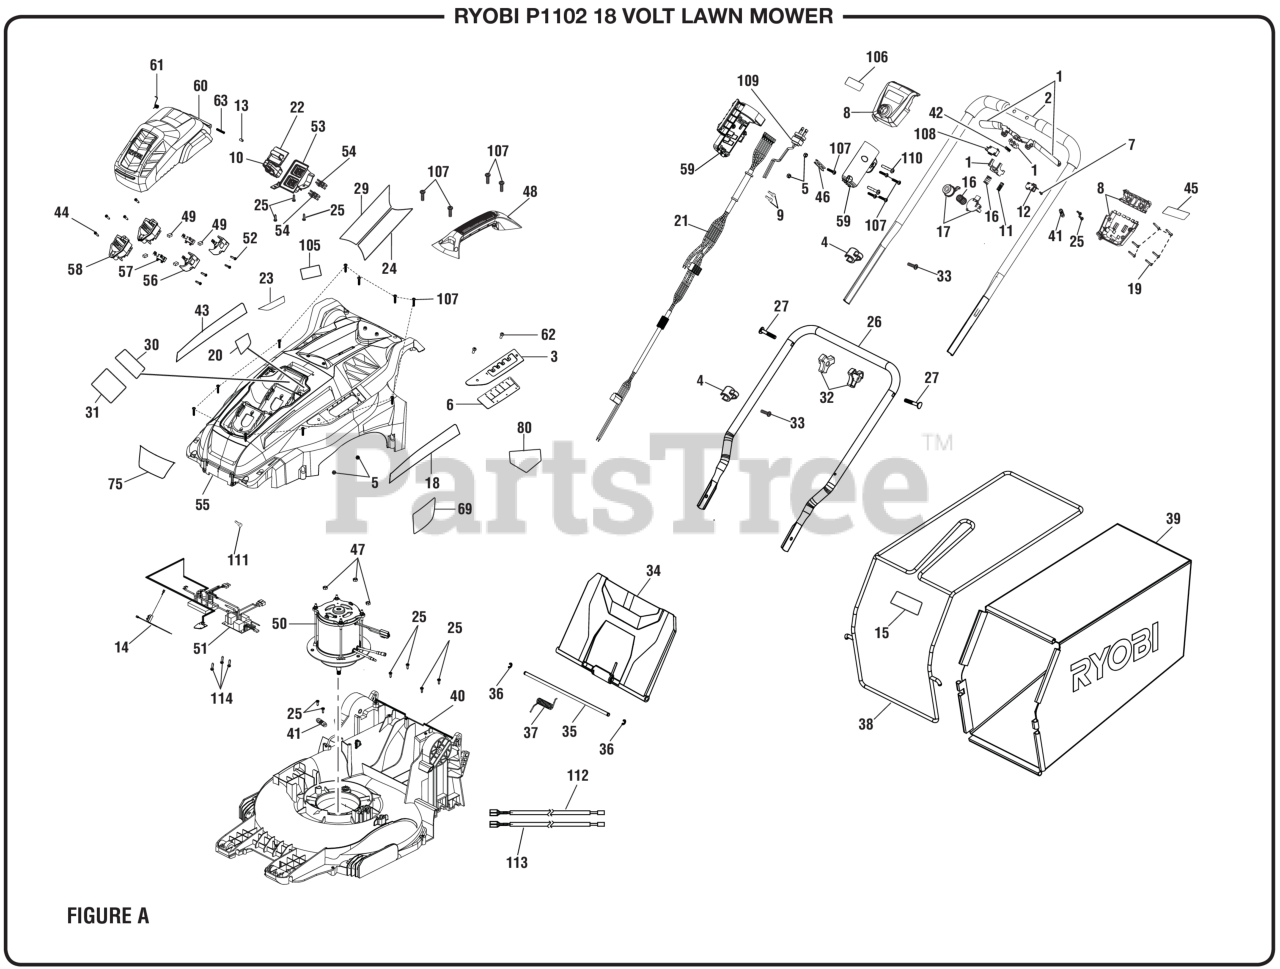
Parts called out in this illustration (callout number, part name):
1	Trigger Handle Assembly
2	Upper Handle Assembly
3	Height Adjustment Plate
4	Cord Clamp
5	Lock Nut (M5 x 0.8 mm)
7	Screw (M4 x 10 mm, T20 Torx Pan Hd.)
8	Trigger Housing Assembly
9	Wire Connector (Closed End)
10	Start Key
11	Compression Spring (Trigger)
13	Battery Door Axle
14	Lead Wire w/Terminal Block
15	Starting Instructions Label
17	Start Button Assembly
18	Lithium Label (Left)
19	Screw (M4-18 x 30 mm, T15 Torx Soc. Hd.)
20	Fuel Gauge Label
21	Starter Cable (Long)
22	Slide Door
23	Icon Warning Label
24	Warning Icon Label (Right)
25	Screw (M4 x 16 mm, T20 Torx Pan Hd.).
27	Screw (M8 x 57 mm)
29	Warning Icon Label (Right)
30	Start Key Label (Eng)
31	Start Key Label (FR/SP)
32	Knob (526906001)
33	Screw (M3 x 20 mm, Pan Hd.)
34	Rear Discharge Door
35	Rear Door Axle
37	Torsion Spring (Rear Door)
38	Bag Frame
41	Wire Press Plate
42	Compression Spring (Trigger Handle)
43	Lithium Label (Right)
44	Screw (M4 x 16 mm, T15 Torx Pan Hd.)
45	Starting Instructions Label
47	Lock Nut (M6)
49	Rubber Cushion
51	Start Circuit Board
52	Screw (M4 x 16 mm, T20 Torx Socket Pan Hd.)
53	Key Holder Assembly
54	Female Terminal
55	Deck Cover
57	Plate (Battery Connect)
58	Base (Battery Connect)
59	AC Plug Housing Assembly
75	Ryobi Logo Label (Handle)
80	Danger Label (No Hands/Feet)
105	Data Label
107	Screw (M4 x 20 mm, T20 Torx Pan Hd. S.T.)
108	Micro Switch
109	Plug Wire
110	Screw (M5 x 30, T20 Torx Pan Hd.)
111	Wire Connector (Closed End)
112	Lead Wire (Red)
113	Lead Wire (Brown)
114	Screw (M3 x 8 mm, Pan Hd., Pan Hd)
